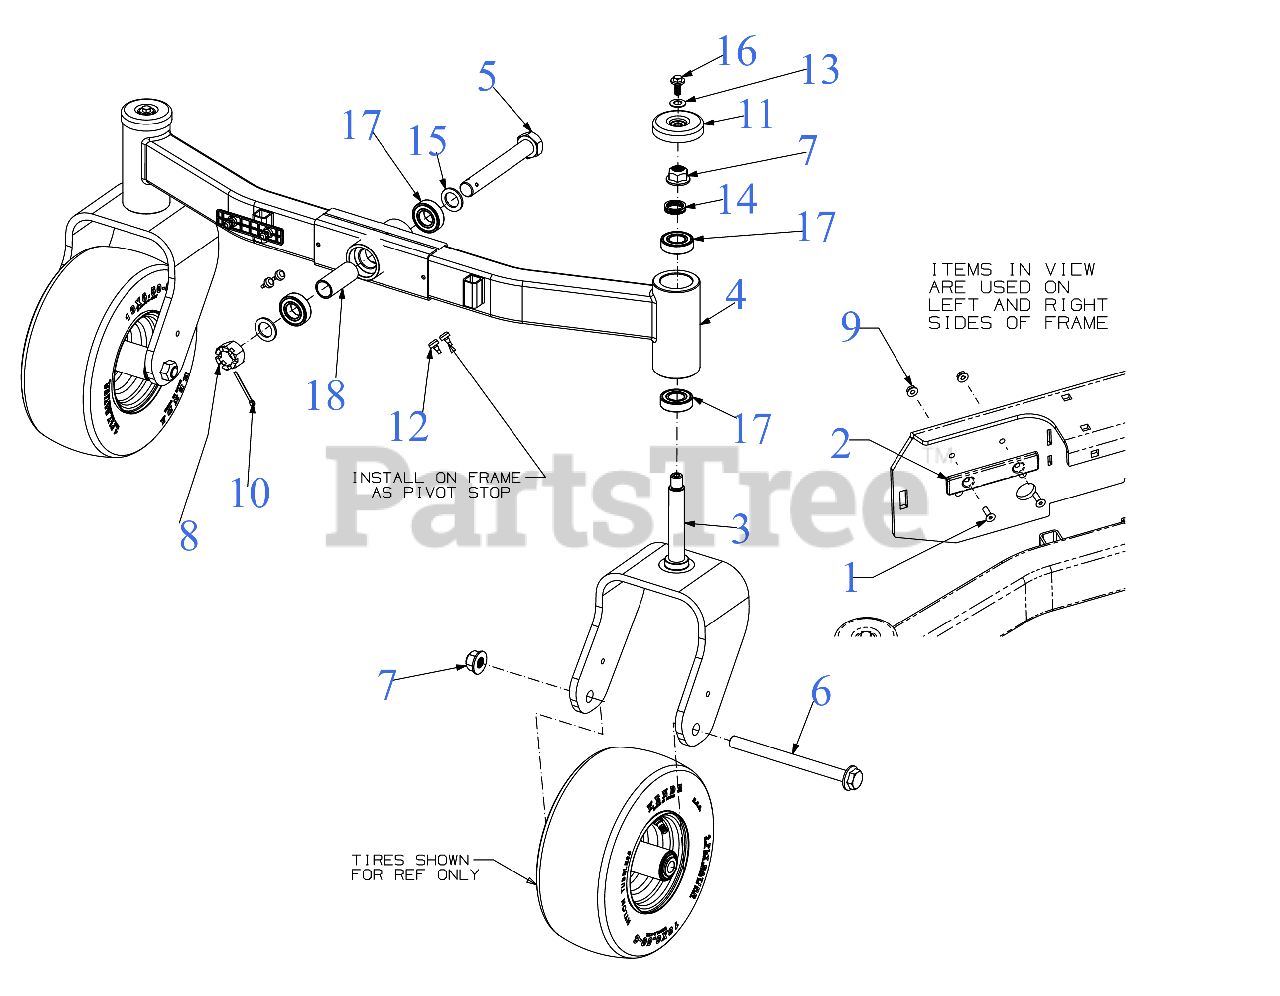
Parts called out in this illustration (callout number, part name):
1	SCREW-FLAT HEAD CA
2	PLATE-LIFT WEAR
5	HEX HEAD SCREW (1-14 x 7 GR5)
6	SCREW 3/4-16 x 9.00 GR5
7	FLANGE LOCK NUT 3/4-16 TOP LOCK
8	CASTLE NUT 1.0-14 GR5
9	LOCK NUT 1/4
10	COTTER PIN
11	AXLE CAP 3"
12	BUMPER, .62 DIA x .3
13	BELL WASHER
14	WAVE WASHER
15	FLAT WASHER 1.005 x 1.570 x 0.125
17	BALL BEARING (1.0 x 52 x 15)
18	SPACER 1.00 x 1.25 x 2.99
